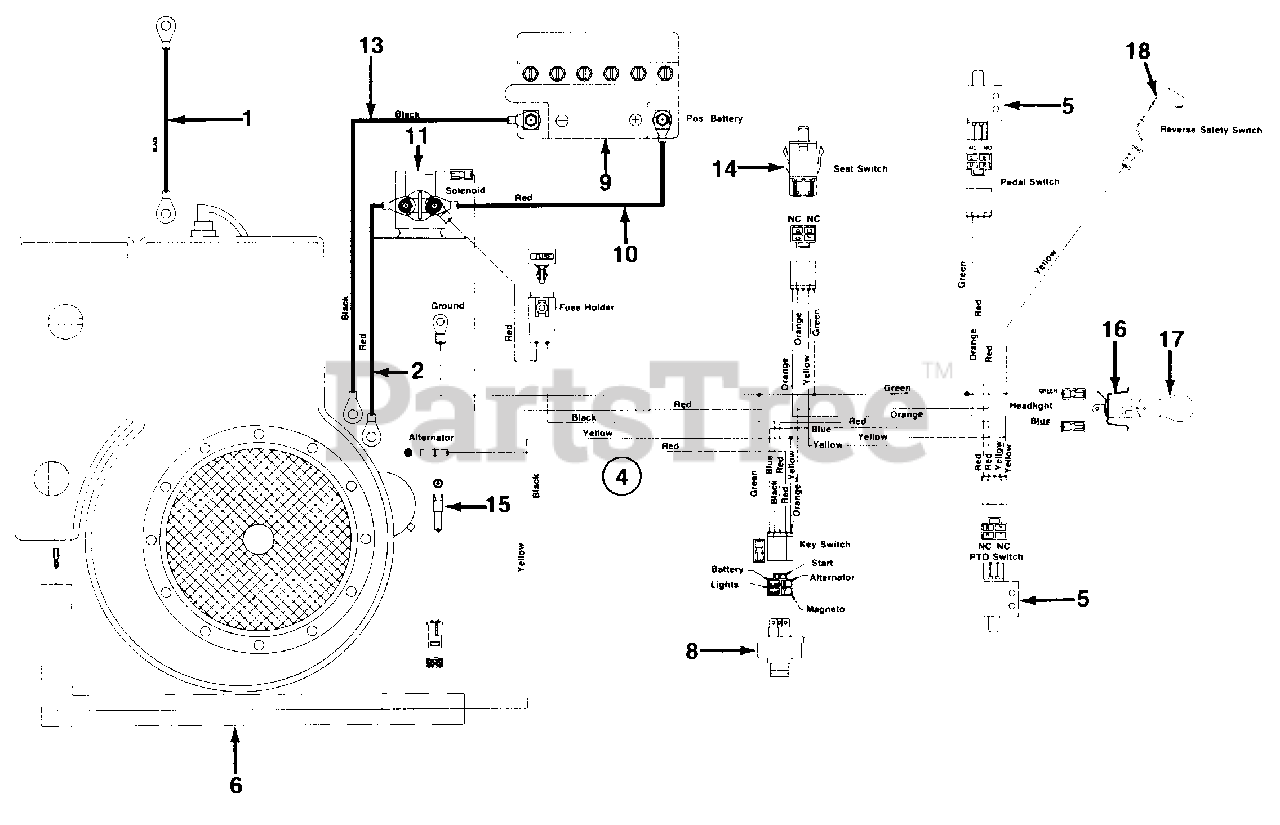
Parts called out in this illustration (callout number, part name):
1	Elec. Wire 8 Ga. x 9.0" Lg.
2	Elec. Wire
4	Wire Harness
5	Safety Switch
6	Convoluted Tubing 29" Lg.
8	Ignition Switch
9	Battery 12V
10	Elec. Wire Red w/Boot
11	Solenoid
13	Elec. Wire 8 Ga. x 17" Lg.
14	Seat Switch
15	Adapter Harness (1208)
16	Headlight Socket
17	Lamp
18	Safety Switch
